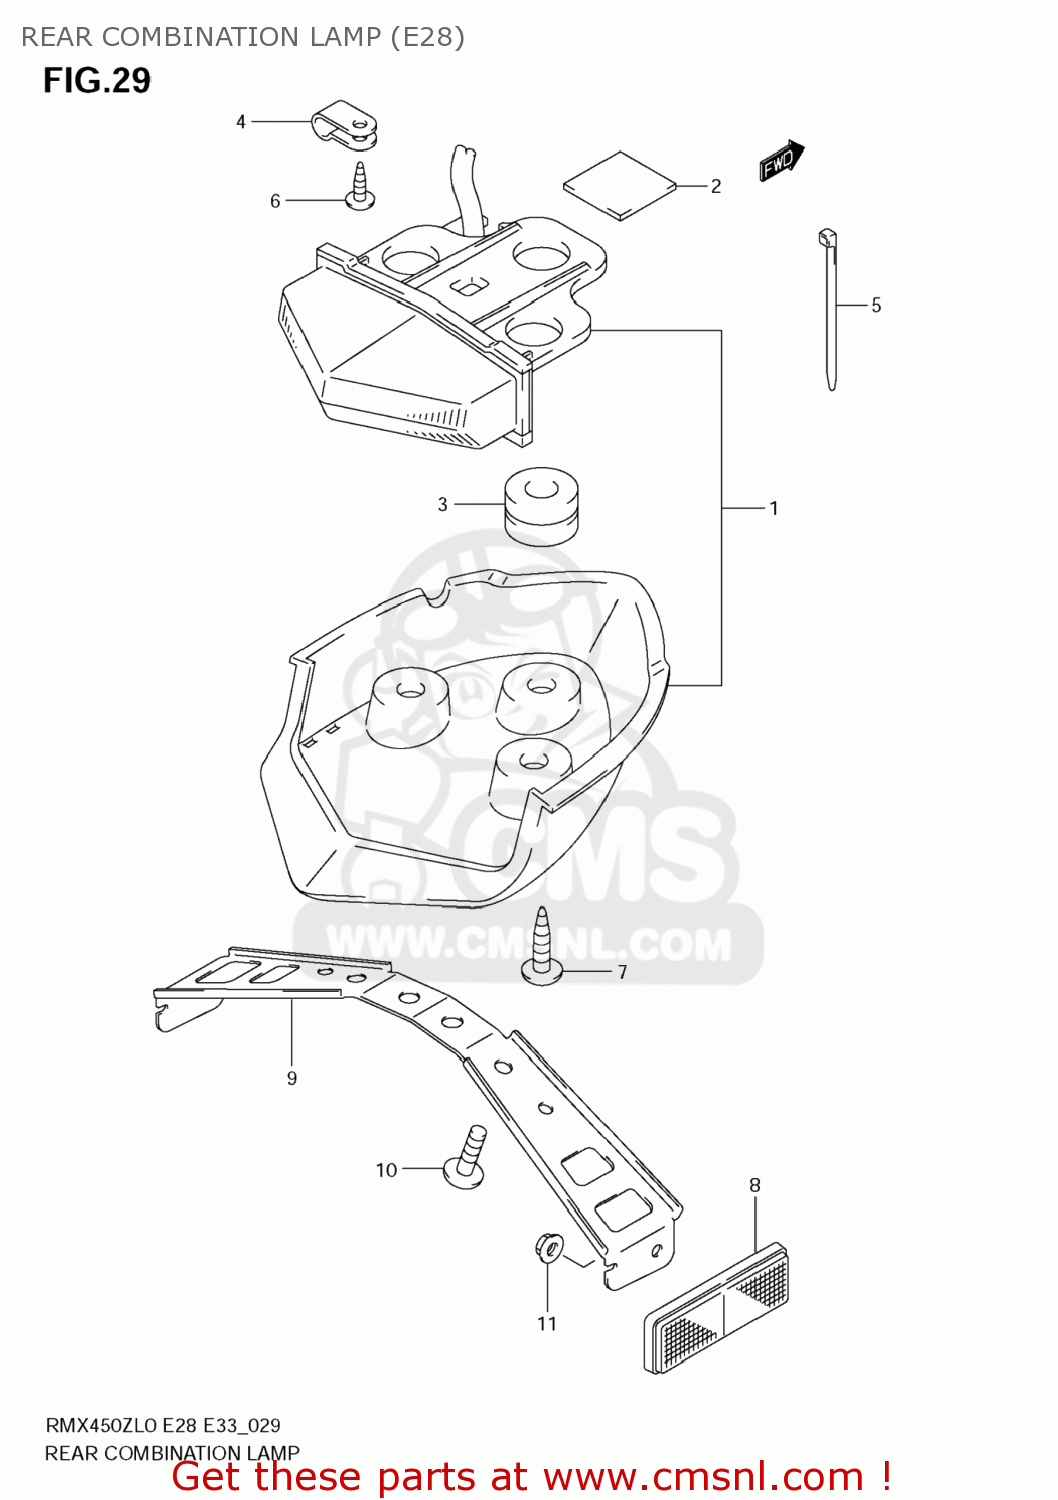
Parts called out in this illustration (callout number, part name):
1	LAMP ASSY,TAIL
2	PROTECTOR,BATTERY(30X40X1.0)
3	CUSHION
4	CLAMP
5	CLAMP(L:145)
6	SCREW
7	SCREW
8	REFLECTOR ASSY,RR
9	BRACKET,RR SIDE RR
10	SCREW
11	NUT
